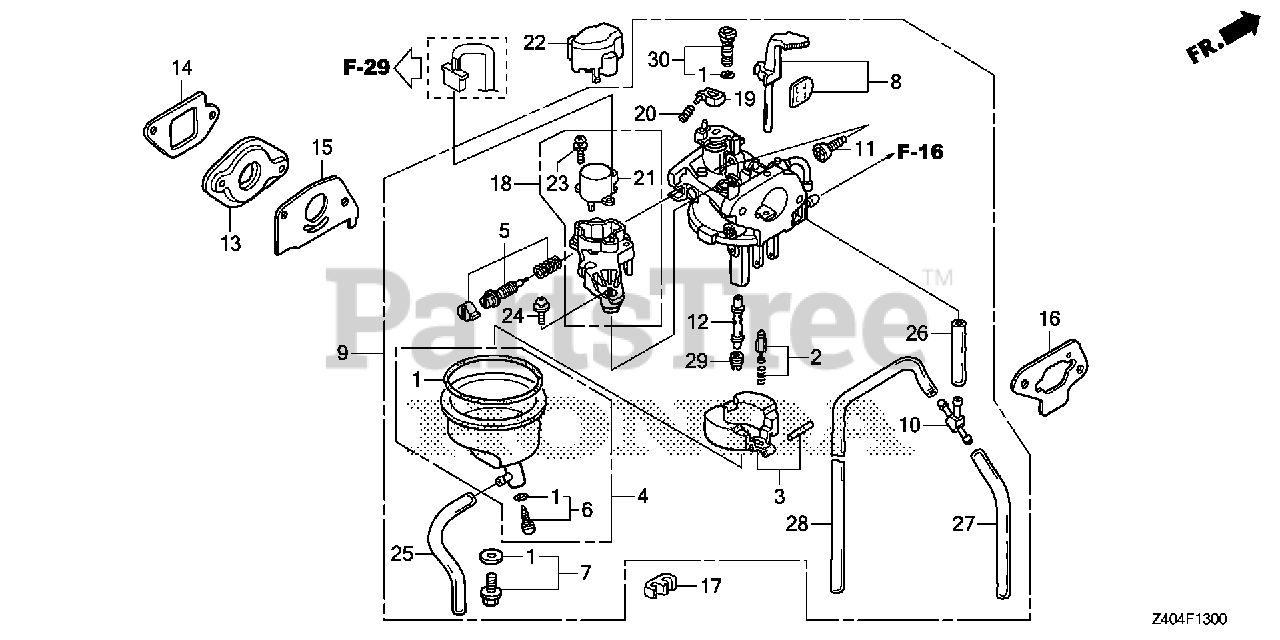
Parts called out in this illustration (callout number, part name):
1	GASKET SET
2	VALVE SET, FLOAT (SEAT NOT INCLUDED)
4	CHAMBER SET, FLOAT
5	SCREW SET, PILOT
6	SCREW SET, DRAIN
7	SCREW SET
9	CARBURETOR ASSY. (BF30C G)
10	JOINT, AIR VENT TUBE
11	SCREW, THROTTLE STOP
12	NOZZLE, MAIN
13	INSULATOR, CARBURETOR
14	GASKET, INSULATOR
15	GASKET, CARBURETOR
16	GASKET, AIR IN. JOINT
17	CLAMP D, IGNITION WIRE
18	MOTOR ASSY., THROTTLE CONTROL
19	LEVER, LINK
20	SPRING, COMPRESSION COIL
21	MOTOR, THROTTLE CONTROL
22	COVER, THROTTLE MOTOR
23	SCREW-WASHER (3X8)
24	SCREW-WASHER (4X10)
25	BULK HOSE, VINYL (3.5X6.5X8000) (3.5X6.5X190)
26	BULK HOSE, VINYL (4X7X8000) (4X7X50)
27	BULK HOSE, VINYL (4X7X8000) (4X7X160)
28	BULK HOSE, VINYL (4X7X8000) (4X7X350)
29	JET, MAIN (#52)
29	JET, MAIN (#55)
29	JET, MAIN (#58)
30	JET SET, PILOT (#35)
